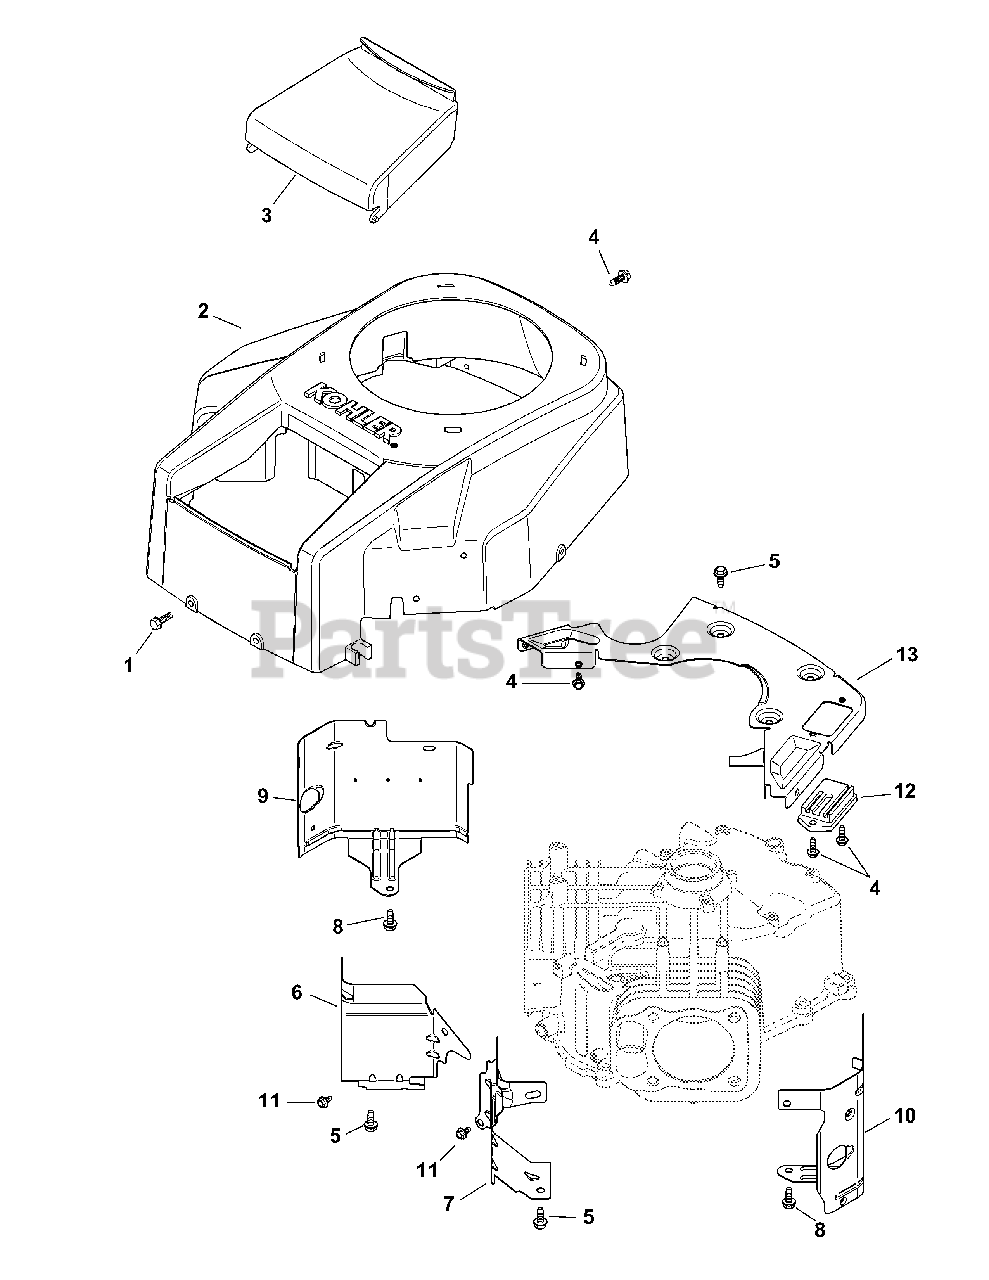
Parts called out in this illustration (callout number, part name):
1	Tap Screw, M6 x 1.7 x 18
2	Housing Blower Kit
3	Air Cleaner Cover
4	Flg. Thd. Frm. Screw, M5 x 0.8 x 16
5	Flg. Thd. Frm. Screw, M6 x 1.0 x 16
6	Valley Baffle - #1 Cylinder
7	Valley Baffle - #2 Cylinder
8	Flng. Thd. Frm. Screw, M6 x 1.0 x 10
9	Cyl Barrel Baffle - #1 Side
10	Cyl Barrel Baffle - #2 Side
11	Flg. Thd. Frm. Screw, M5 x .8 x 10
12	Regulator/Rectifier
13	Backing Plate Kit
